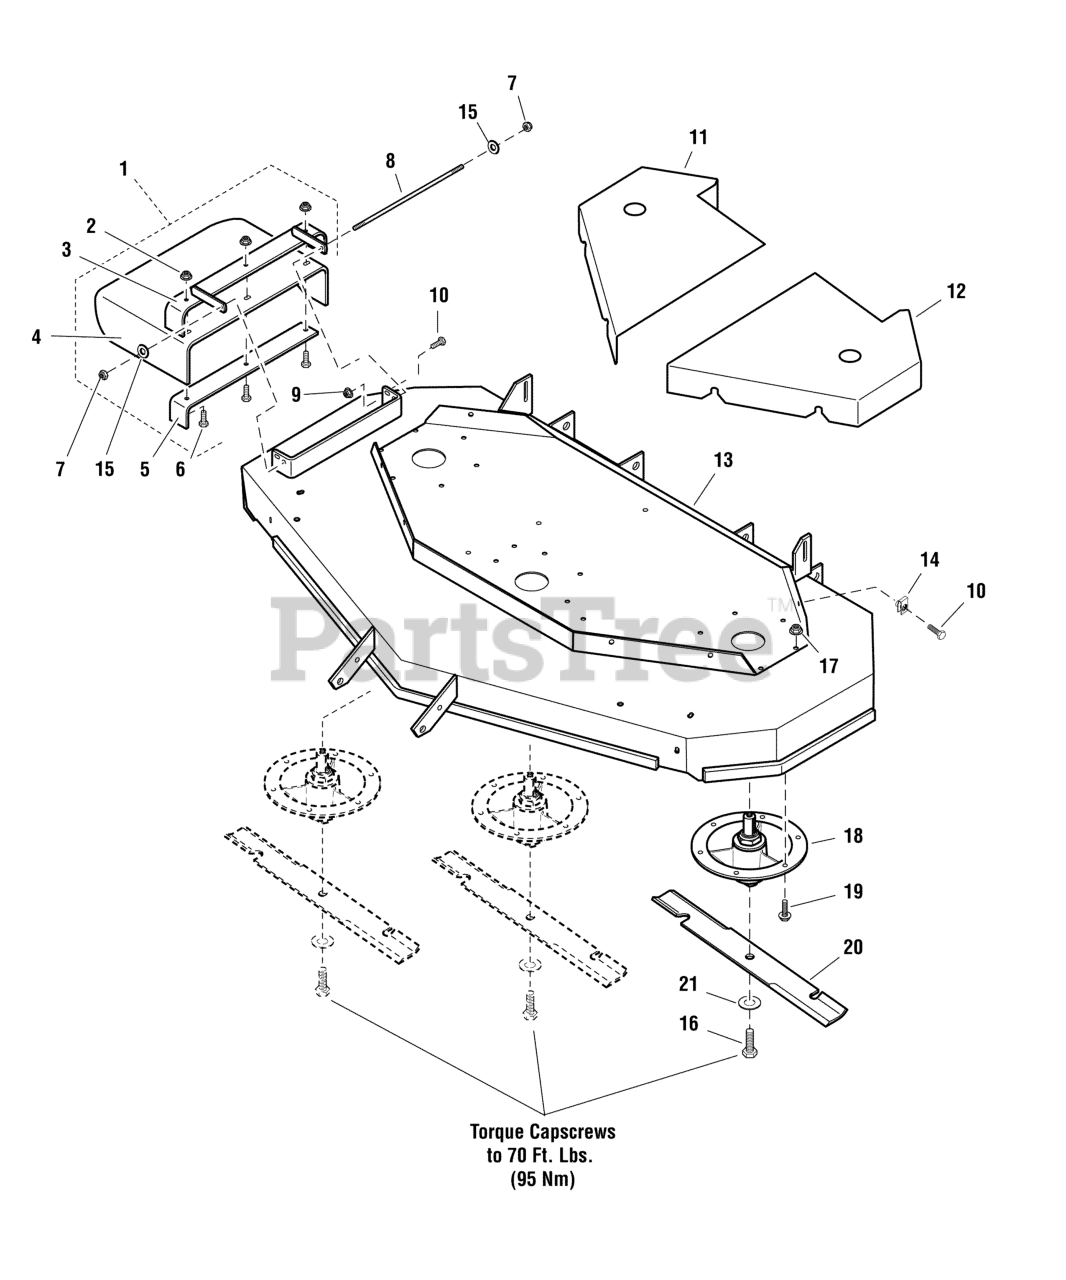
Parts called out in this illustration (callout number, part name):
1	61" / 72" RUBBER CHUTE ASSEMBLY, Complete
2	NUT, 3/8-16 HEX NYLOCK FLANGE
3	WELD, FRAME, CHUTE, 61 / 72 - RED
4	CHUTE, DISCHARGE, RUBBER, 61 / 72
5	SUPPORT, DISCHARGE CHUTE - BLK
6	BOLT, 3/8-16 X 1-1/4" GD5 CZ
7	NUT, 5/16-24 HEX NYLON LOCK
8	ROD MOUNT, CHUTE
9	NUT, 5/16-18 HEX NYLOCK FLANGE
10	SCREW, 5/16-18x0.750, GR5, WHIZ-LOCK, ZC
11	GUARD 72" - RH - RED
12	GUARD 72" - LH - RED
13	DECK SHELL W/ DECALS (SV)
14	BODY CLIP, 5/16-18-7GA MATERIAL
15	WASHER, 5/16 GR.9 FLAT
16	BOLT, 5/8-11 X 1-3/4" GD8
17	NUT, 3/8-16 HEX NYLOCK FLANGE
18	ASSM, SPINDLE, BOTTOM MOUNT
19	BOLT, 3/8-16 X 1, FLANGE, GD 5, CZ
20	BLADE, 25" (SET OF 3)
21	WASHER, 5/8" GRADE 8, YZ
